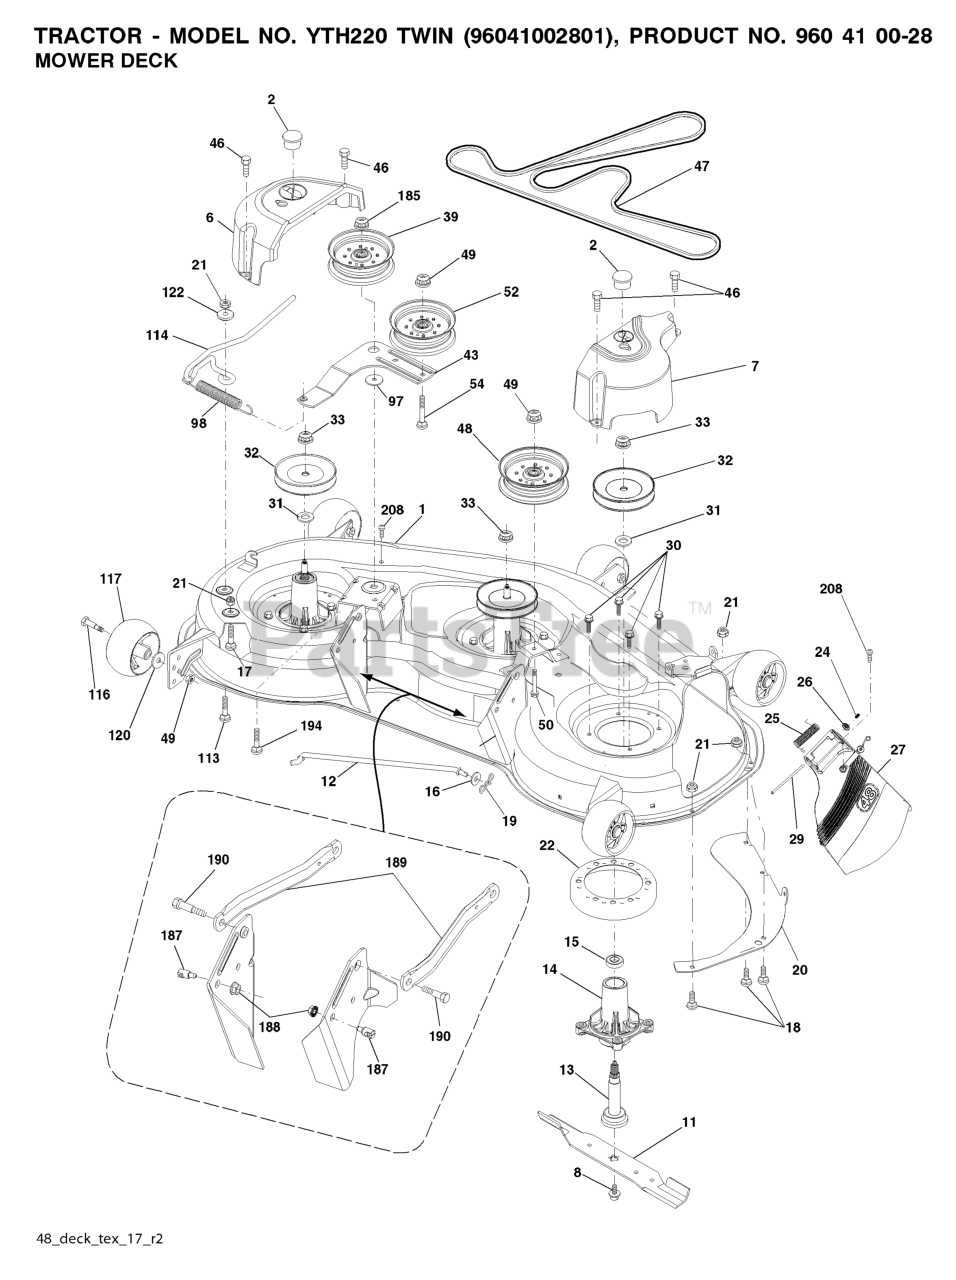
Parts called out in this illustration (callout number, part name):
1	DECK WELDMENT
8	BOLT 7/16 ASM BLADE
11	48" HI-LIFT BLADE
12	ROD.ANTI.SWAY.48/54"K4
13	SHAFT ASM MANDREL
14	RP.HOUSING.MANDREL.4PT.
16	WASHER
17	BOLT.CARR.5/16-18X5/8.SHORT
18	BOLT
19	PIN.COTTER.5/16.BOW TI
20	BAFFLE, VORTEX MWR
21	LOCKNUT
22	STRIPPER.MANDREL.ROUND.BLACK
24	CAP-SLEEVE LT
25	SPRING, TORSION
26	NUT PUSH M
29	ROD.HINGE
30	SCREW, WASHER HEAD
31	WASHER.SPACER.MANDREL
32	PULLEY MANDREL
33	NUT.FLANGE.LOCK.TOP
39	RB PULLEY.IDLER.4.50/HUB SPEC
46	SCREW.1/4-20X5/8
47	BELT.DRIVE.DECK
48	PULLEY.IDLER.48"PRIMARY
49	NUT LOCK FLG 3/8-16 UNC
50	SCREW TT 3/8-16X2-1/4 UNC
52	PULLEY.IDLER.2006
54	BOLT.3/8-16X1.50
98	SPRING, DECK DRIVE
114	ROD.TENSION.RELIEF.TEX (2 2)
116	BOLT.SHOULDER.3/8-16X3-5/8.
117	RP WHEEL. GUAGE RALLY
120	WASHER
122	BUSHING.RELIEF.TENSION
185	NUT.LOCK.FLANGE.7/16
187	STUD.FASTNER.W/ANTI-ROTATE
188	NUT LOCK HEX FLANGE 5/16-18
189	ARM.SUSPENSION.MOWER
190	BOLT.SHOULDER
194	BOLT.CARR.SQNK.7/16
208	SCREW 3/8-16X1/2
